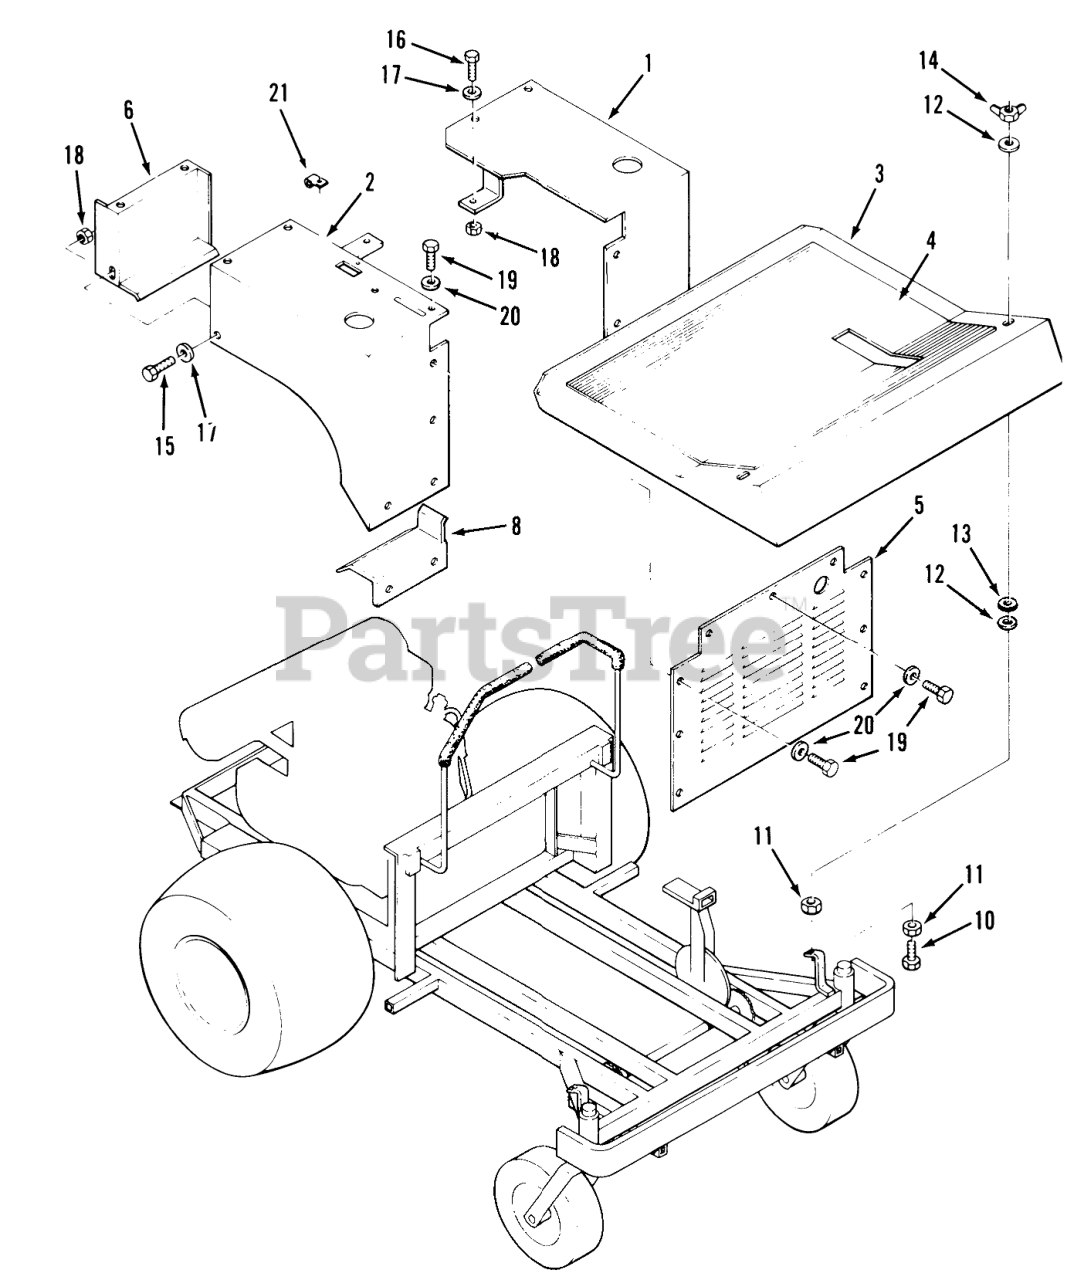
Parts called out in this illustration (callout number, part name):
1	Fender LH
2	FENDER WA RH R
3	Floor Pan
4	Black Carpet
5	Front Panel
6	Bracket-Fender Rear RH
8	Bracket-Fender Frt RH
10	SCREW-HH
11	NUT-HEX
12	WASHER-FLAT
13	WASHER
14	WING NUT
15	SCREW-HH
16	SCREW-HH
17	WASHER-FLAT
18	NUT-LOCK, NI
19	SCREW-HWH
20	WASHER-FLAT
21	J-CLIP
